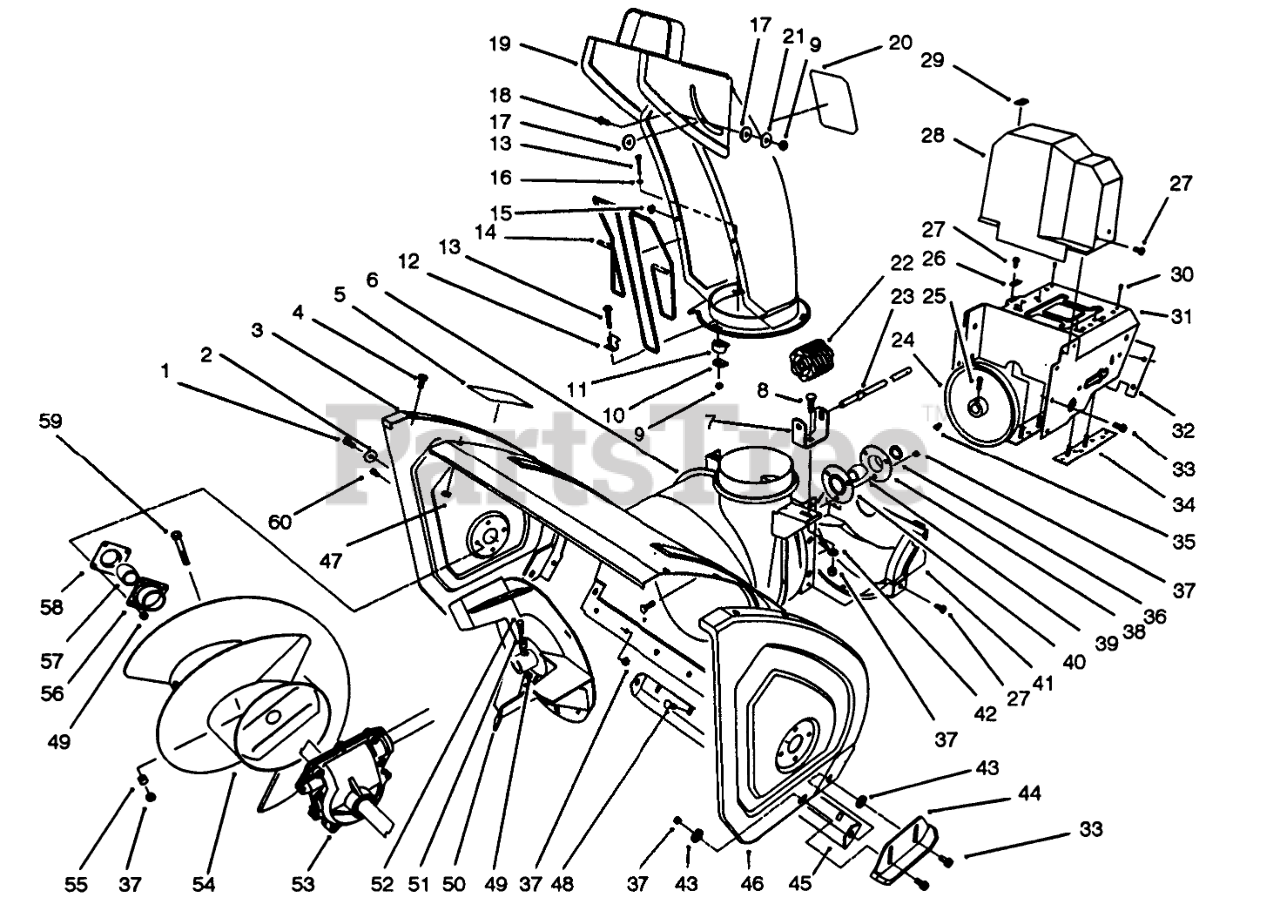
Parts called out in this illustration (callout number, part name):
1	SCREW-HH
2	WASHER
3	Plate-Side
4	SCREW-HHF
5	DECAL-WARNING, AUGER
6	Housing-24 Inch
7	BRACKET-WORM, CHUTE
8	BOLT-CARR
9	NUT-LOCK, NI
10	PLATE-RETAINER, CHUTE
11	RETAINER-CHUTE
12	CLIP-GUARD, CHUTE
13	SCREW-HSH
14	GUARD-CHUTE
15	NUT-PUSH
16	WASHER-FLAT
17	WASHER-PLASTIC
19	Assembly
20	Decal-Danger
21	WASHER-FLAT
22	GEAR-WORM
23	ROD-CHUTE, LOWER
24	PULLEY-IMPELLER
25	SCREW-SET, SQH
26	RETAINER-CABLE
27	SCREW-HWH
28	COVER-BELT, UPPER
29	COVER-CABLE
30	RIVET-POP
31	Frame-Engine
32	Cover-Frame, Engine
33	SCREW-HHF
34	LH FRAME PLATE ASM
35	KEY-WOODRUFF
36	WASHER-THRUST
37	NUT-LOCK, NI
38	Flange-Bearing (Front)
39	BEARING-BALL
40	Flange-Bearing (Rear)
41	COVER-BELT, LOWER
42	WASHER-PLAIN
43	WASHER
44	Skid
45	Blade-Scraper
46	Plate-Side
47	NUT-LOCK, NI
48	SCREW-CARR
49	NUT-LOCK, NI
50	Impeller
51	SPACER
52	SCREW-HHF
53	AUGER GEARCASE ASM
54	Auger-RH
55	SPACER-HUB, AUGER
56	BEARING-FLANGE, FRONT
57	BEARING
58	BEARING-FLANGE, REAR
59	Auger Bolt
60	SCREW-HH
